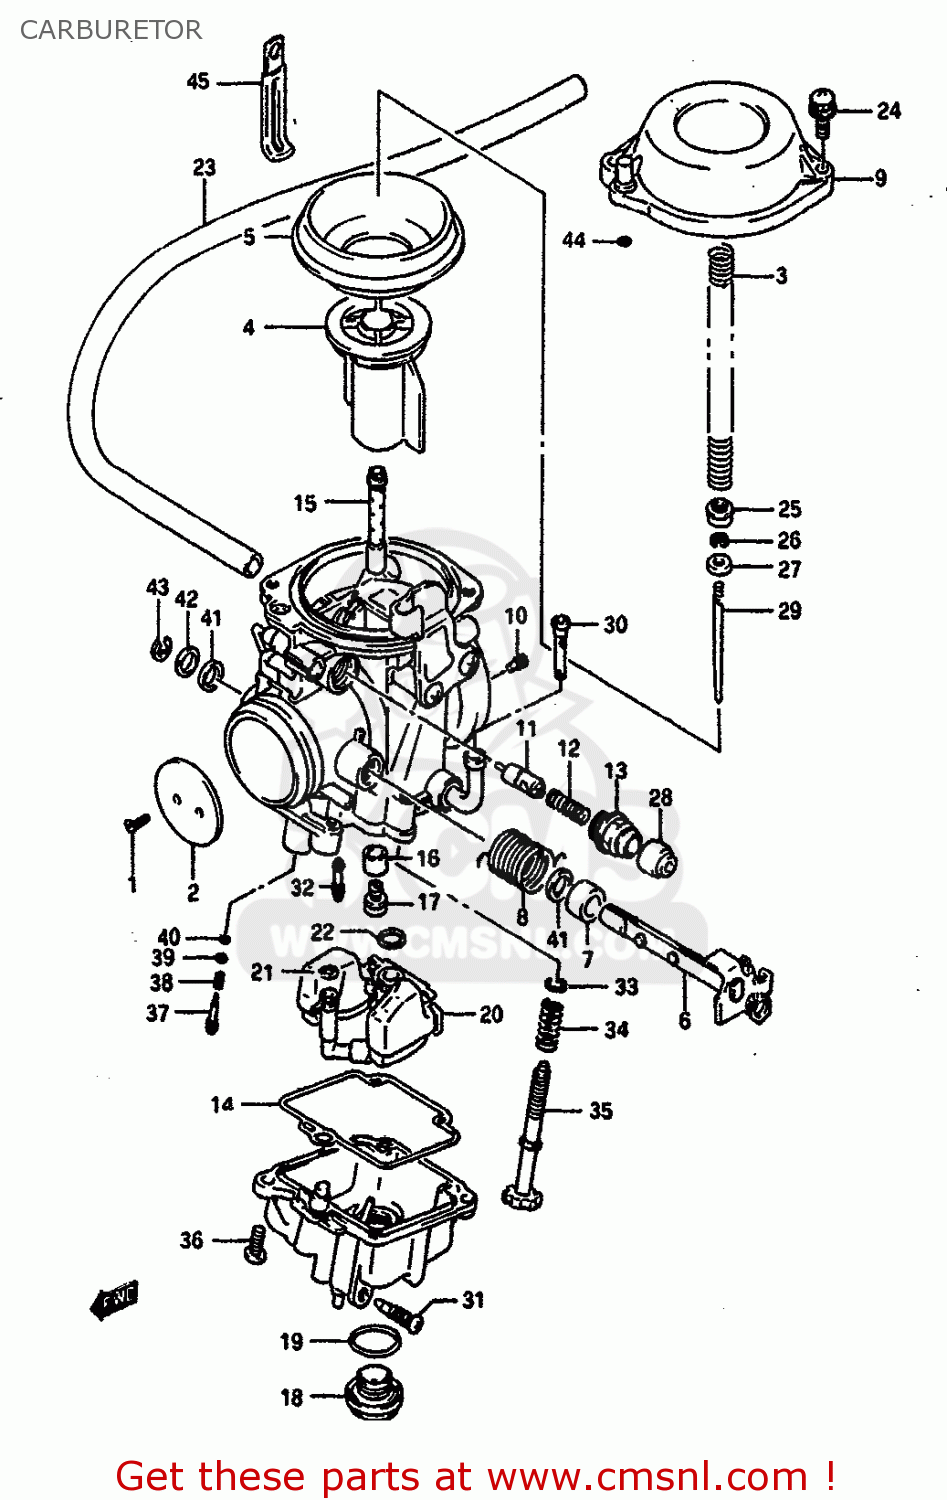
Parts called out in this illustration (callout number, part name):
1	SCREW
2	VALVE,THROTTLE
3	SPRING
4	VALVE,PISTON
5	DIAPHRAGM
6	SHAFT ASSEMBLY,THROTTLE
7	RING
8	SPRING
9	COVER,DIAPHRAGM
10	JET,AIR(1.3)
11	PLUNGER
12	SPRING
13	HOLDER,GUIDE
14	GASKET,FLOAT CHAMBER (NAS)
15	JET,NEEDLE
16	RING
17	JET
18	SCREW,GUIDE
19	O RING,DRAIN PLUG
20	FLOAT/NEEDLE VALVE ASSEMBLY
21	O RING
22	O-RING,NEEDLE VALVE
23	HOSE (6.5X10.5X475)
24	SCREW
25	RING
26	CLIP,NEEDLE
27	RING
28	CAP
29	NEEDLE JET
30	FILTER
31	PLUG,DRAIN
32	JET,PILOT(45)
33	WASHER
34	SPRING
35	SCREW
36	SCREW
37	SCREW,PILOT
38	SPRING
39	WASHER
40	O RING,PILOT AIR SCREW
41	SEAL
42	GASKET,THROTTLE SHAFT (NAS)
43	E RING
44	O RING
45	CLAMP
